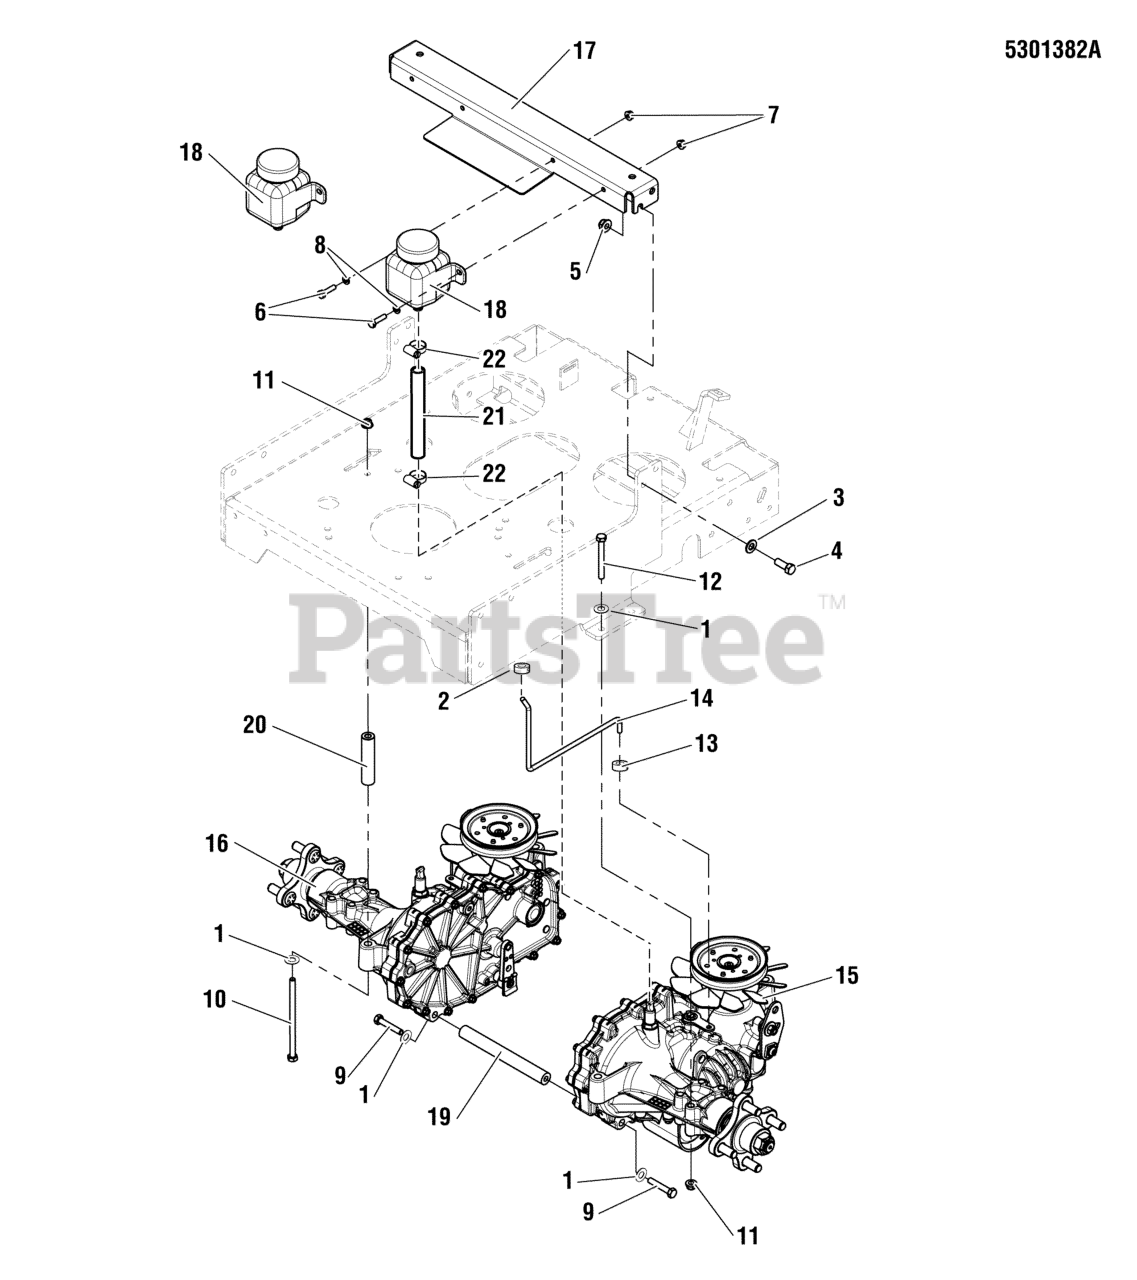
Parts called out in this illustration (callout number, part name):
1	WASHER, 5/16 GD.9 FLAT
2	COLLAR, 5/16 SET
3	WASHER, 3/8 SAE
4	BOLT, 3/8-16 X 1" GD5 CZ
5	NUT, 3/8-16 HEX NYLOCK FLANGE
6	BOLT, 1/4-20 X 3/4", GD5
7	NUT, 1/4-20 HEX NYLOCK FLANGE
8	WASHER, 1/4 SAE
9	BOLT, 5/16-18 X 2-1/4 GD5 YZ
10	BOLT, 5/16-18 X 5-1/2, GD 5, YZ
11	NUT, 5/16-18 HEX NYLOCK FLANGE
12	BOLT, 5/16-18 X 2-3/4, GD 5, YZ
13	COLLAR, 1/4" SET
14	ROD, HYDRO RELEASE, SNP PRO WB
15	TRANSMISSION, LH, HG ZH-GMBB-3A5A-1LLX
16	TRANSMISSION, RH, HG ZH-KMBB-3A5A-1LLX
17	PLATE, HYD TANK MOUNT - RED
18	RESERVOIR, HYDRO OIL, 350 ML
19	SPACER, HYDRO LINK, SNP PRO WB
20	SPACER, .34 X .75 X 3.27, YZ
21	HOSE, 1/2" X 4.25 PUSH-ON
22	CLAMP, HOSE, .75 FREE DIA.
